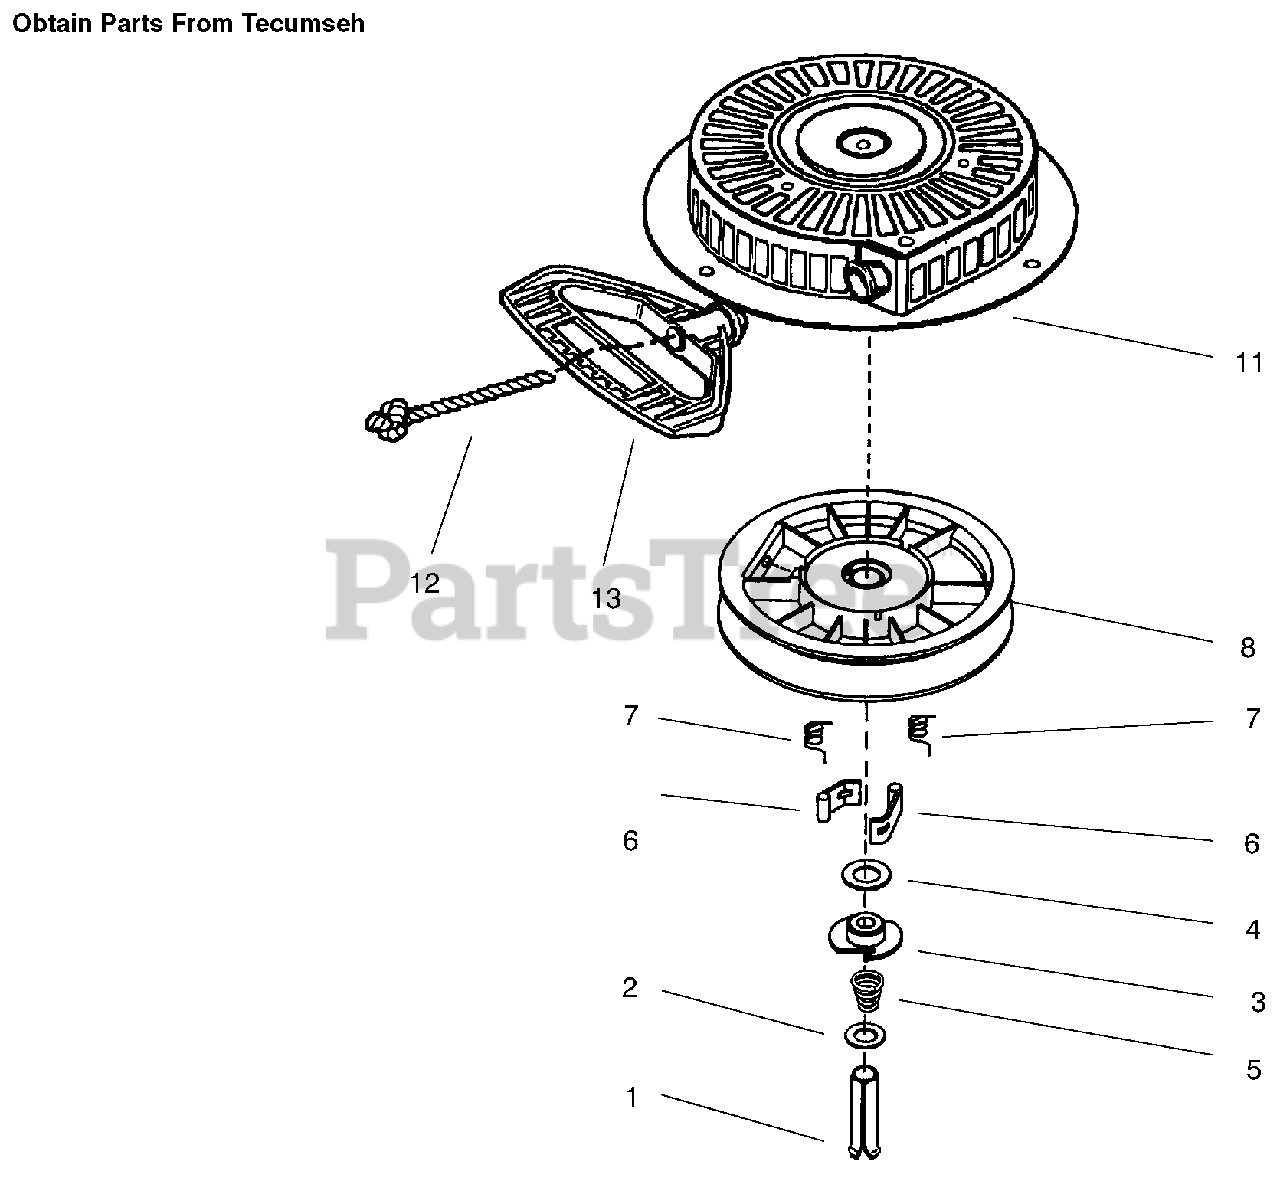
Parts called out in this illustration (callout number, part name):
1	Pin-Spring (Incl. Ref. #4)
3	Retainer
5	Spring-Brake
6	Dog-Starter
7	Spring-Dog
8	Pulley & Rewind Spring Assembly
11	Starter Housing Asm
12	Rope-Starter
13	Handle-Mitten Grip
